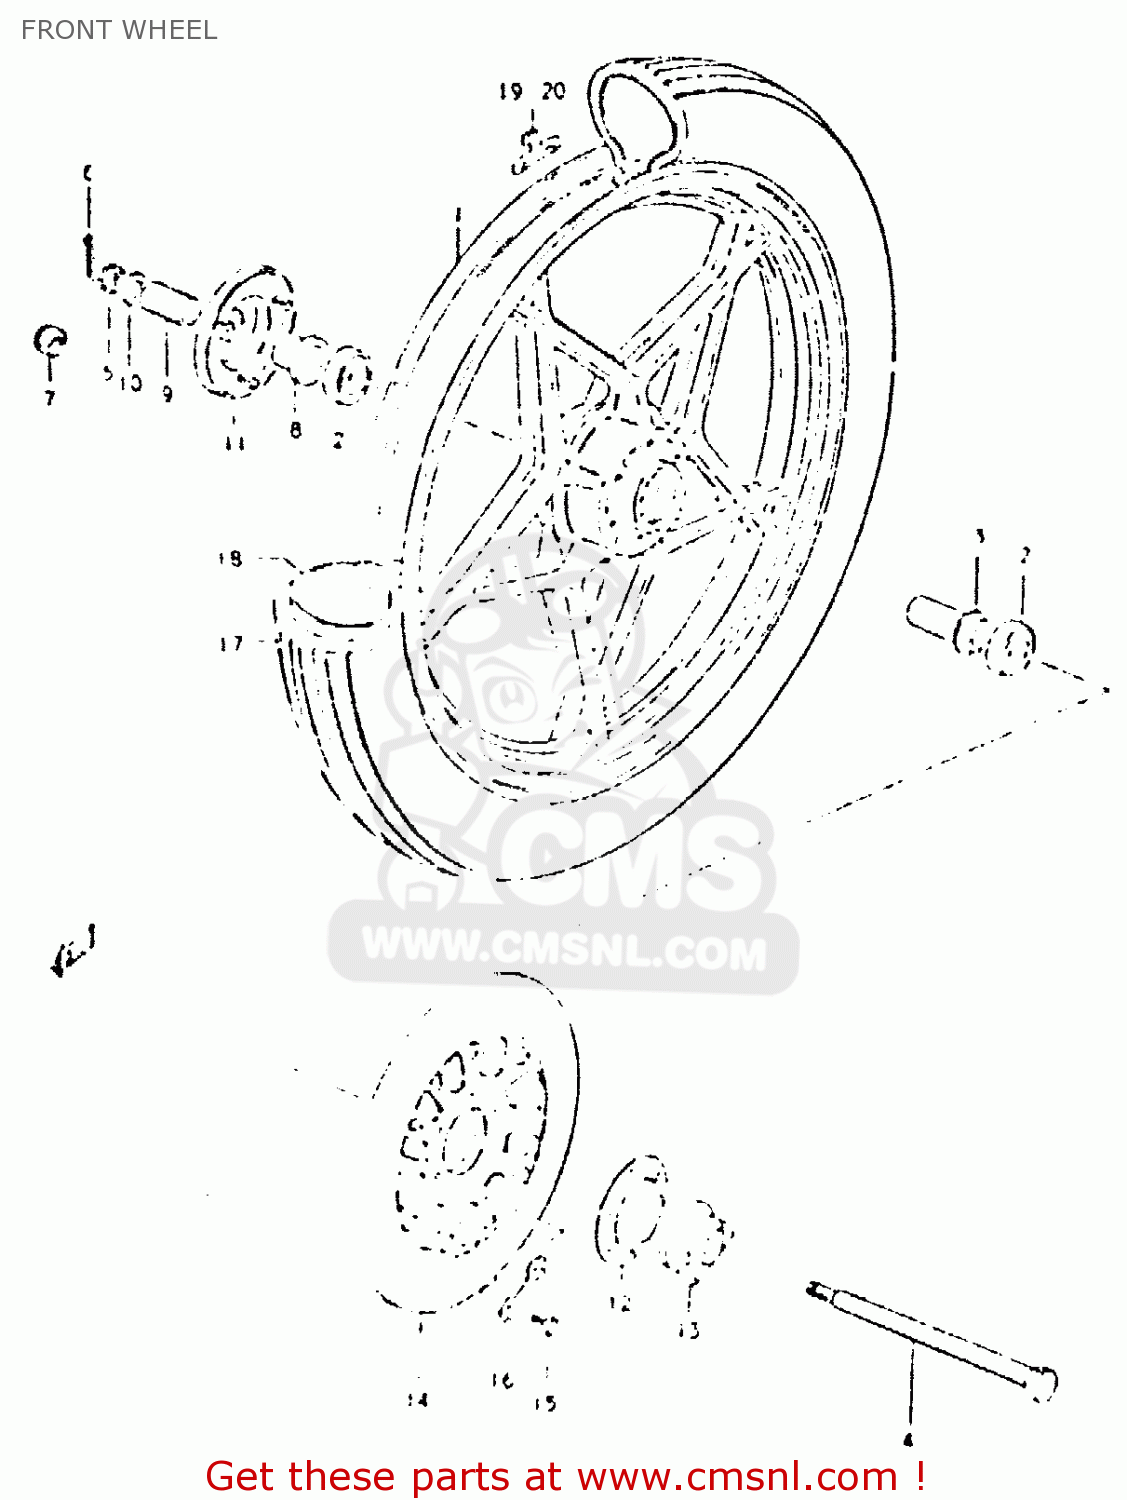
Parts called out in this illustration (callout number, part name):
1	WHEEL, FRONT
2	BEARING
3	SPACER,FR HUB BEARING
4	AXLE,FRONT
5	NUT 12MM
6	COTTER PIN
8	SPACER,FR HUB BEARING,R
9	SPACER(15X22X30)
10	WASHER
11	COVER,FR HUB,R
12	DUST SEAL,SPEEDOMETER GEAR BOX
13	BOX ASSEMBLY,SPEEDOMETER GEAR
14	DISC,FR BRAKE
15	BOLT(8X25)
16	WASHER
17	TIRE,FRONT
18	TUBE,INNER
19	BALANCER,WHEEL
20	BALANCER,WHEEL
